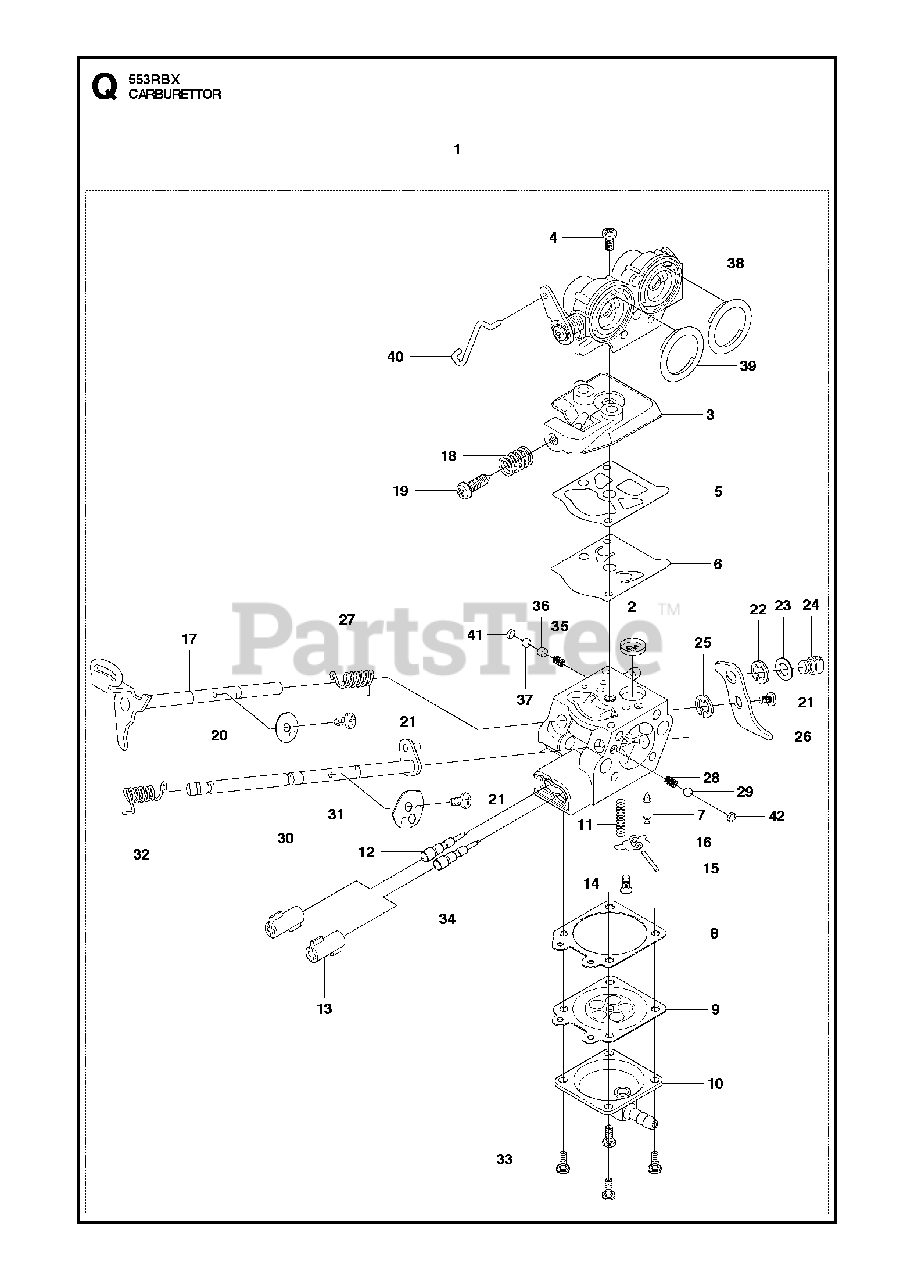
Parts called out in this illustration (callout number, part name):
2	SCREEN
3	COVER
4	SCREW
5	GASKET
6	DIAPHRAGM,PUMP(RPLS-330481150)
7	RP VALVE INLET
8	GASKET METERING
9	DIAPHRAGM
10	COVER
11	SPRING
12	NEEDLE, IDLE
13	CAP
16	LEVER
18	SPRING
19	SCREW, IDLE ADJ
20	RP_VALVE
22	RING
23	WASHER
24	SWIVEL***
25	E-RING
26	LEVER, THROTTLE
27	SPRING RETURN
28	SPRING
29	BALL, FRICTION
30	SHAFT, CHOKE
31	ACCELATOR
32	SPRING, RETURN
34	NEEDLE
35	SPRING
38	BODY ASSY
40	LINK ROD
41	PLUG
